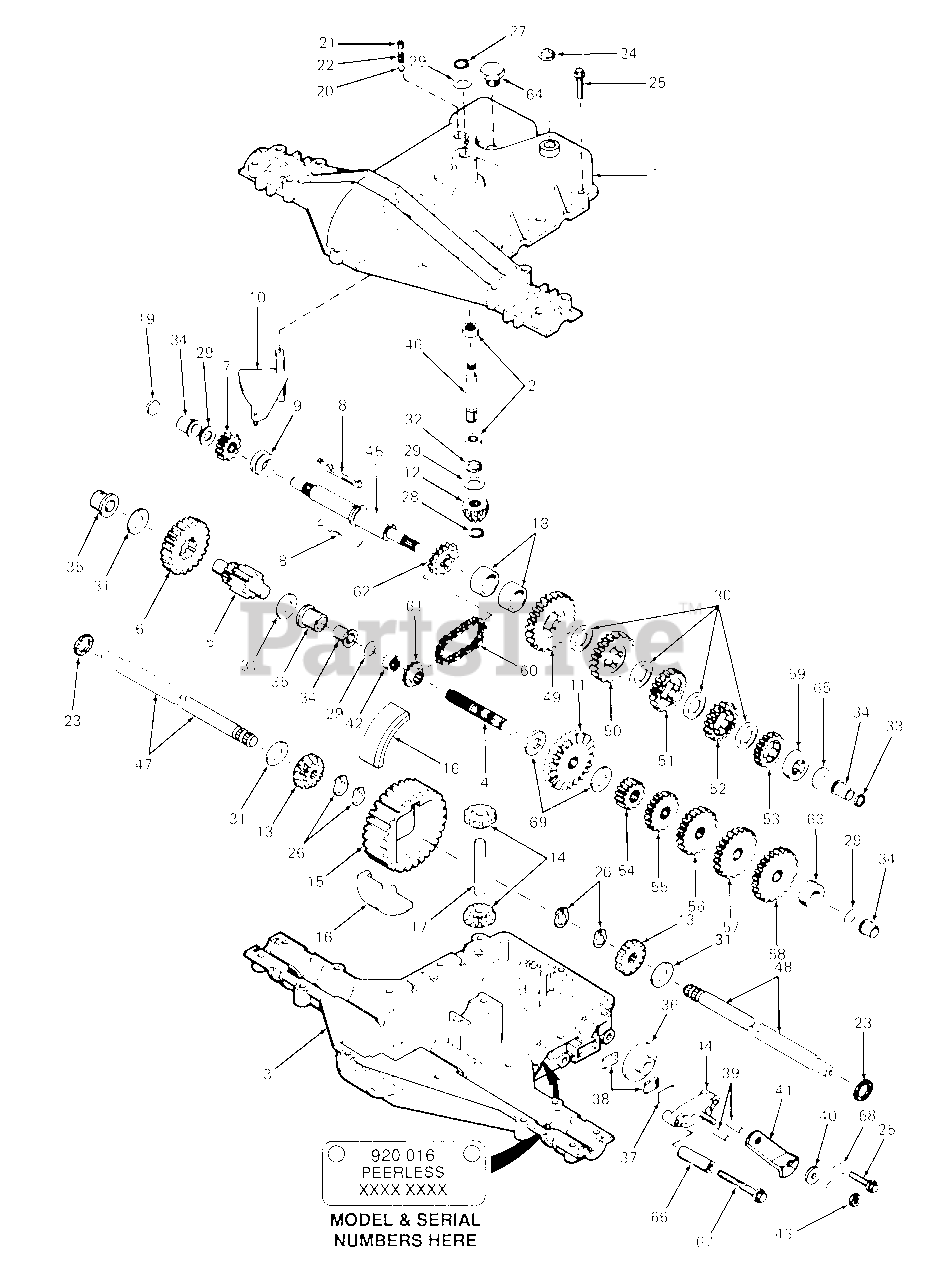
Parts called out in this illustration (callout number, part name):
1	Cover, Transaxle
2	Bearing, Needle
3	Case, Transaxle
4	Shaft, Counter
5	Shaft & Pinion Assy, Output
6	Gear, Output
7	Gear, Spur - 1st
9	Collar, Shifter
10	Rod & Fork Assy, Shift
11	Gear, Bevel (42 Teeth)
12	Gear, Bevel Input
13	Gear, Bevel
14	Gear
15	Gear, Ring
16	Block, Bearing
17	Pin, Drive
18	Spacer, Neutral
19	Disk
20	Ball, 5/16 Dia, Grade 200
23	Ring, Seal
24	Seal, Square Cut
25	Screw, Flanged Hex, 1/4-20 X 1.25 Lg
26	Ring, Retainer (Set of 2)
27	Ring, Retaining
28	Ring, Ext Ret, .521
29	Washer, Thrust
32	Ring, Quad
33	Ring, Sq Cut
34	Bushing, Flanged
36	Brake, Disc
37	Plate, Brake Pad
38	Pad
39	Pin, Dowel
40	Washer, Flat, .344 X 1.0 X.063 HDN
41	Lever, Brake
43	Nut
44	Holder, Brake Pad
45	Shaft, Brake
46	Shaft, Input
47	Axle, 11.62 Lg
48	Axle, 16.0 Lg
49	Gear, Spur (37 Teeth)
50	Gear, Spur (30 Teeth)
51	Gear, Spur (25 Teeth)
52	Gear, Spur (22 Teeth)
53	Gear, Spur (20 Teeth)
54	Gear, Spur (12 Teeth)
55	Gear, Spur (20 Teeth)
56	Gear, Spur (25 Teeth)
57	Gear, Spur (28 Teeth)
58	Gear, Spur (30 Teeth)
60	Chain, Roller
61	Sprocket (9 Teeth)
62	Sprocket (18 Teeth)
65	Washer, Thrust
67	Screw, Hex Flanged Hd, 1/4-20 X 2-1/4 Lg
68	Bracket, Brake Lever
69	Washer, Thrust
